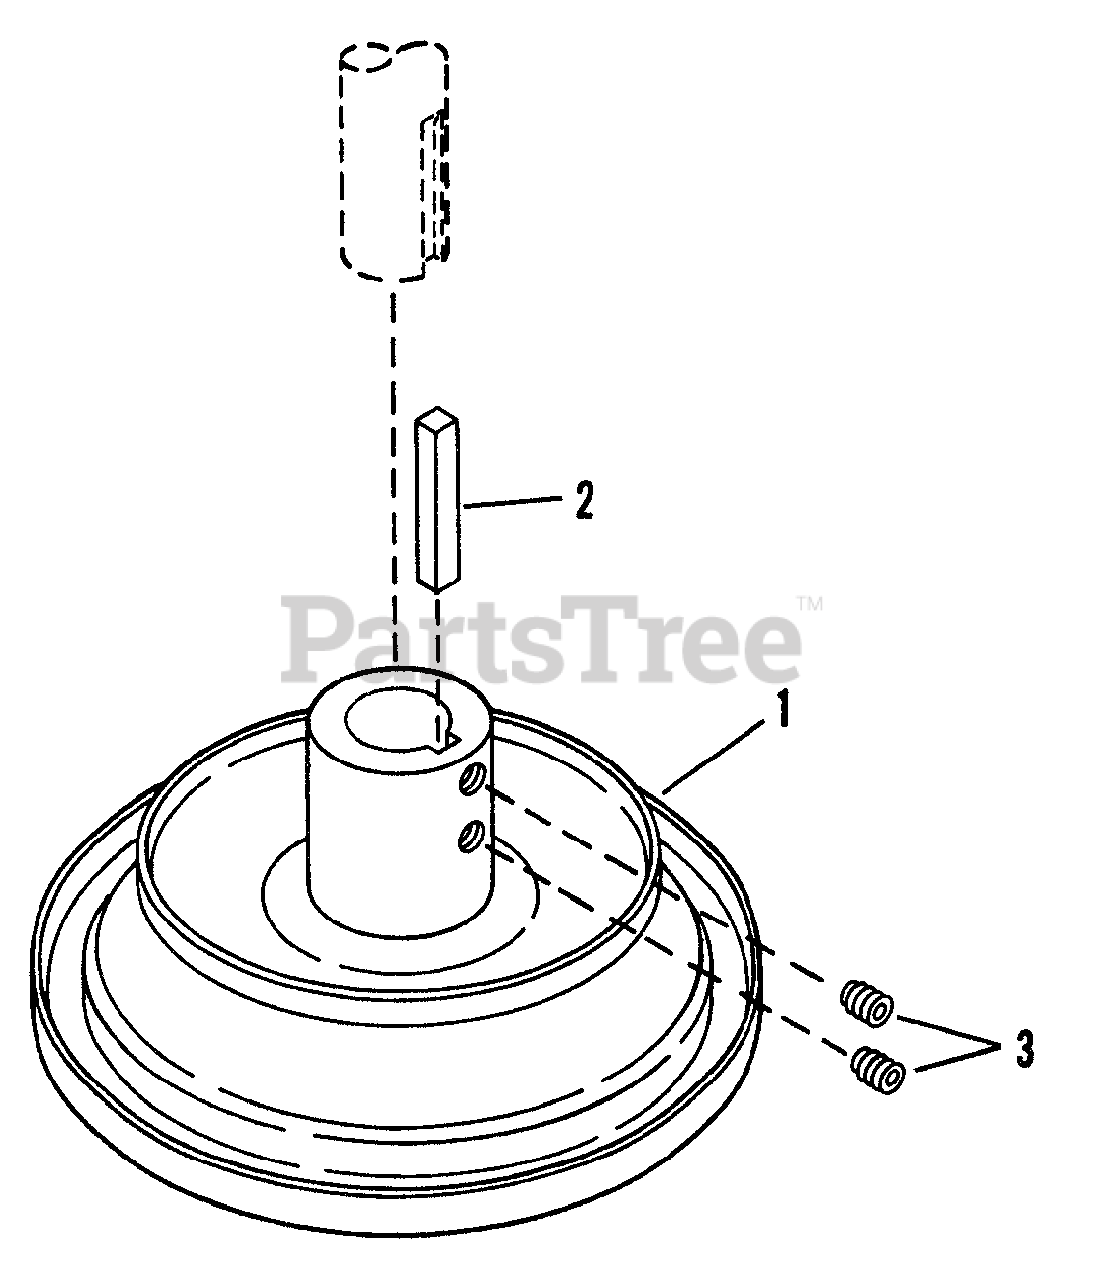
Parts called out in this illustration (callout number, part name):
1	ASSEMBLY, Drive Disc, 5" O.D.for 25,26, & 28" Models
2	KEY, 1/4x1/4x2"
3	SET-SCREW, 3/8-16x3/8"
